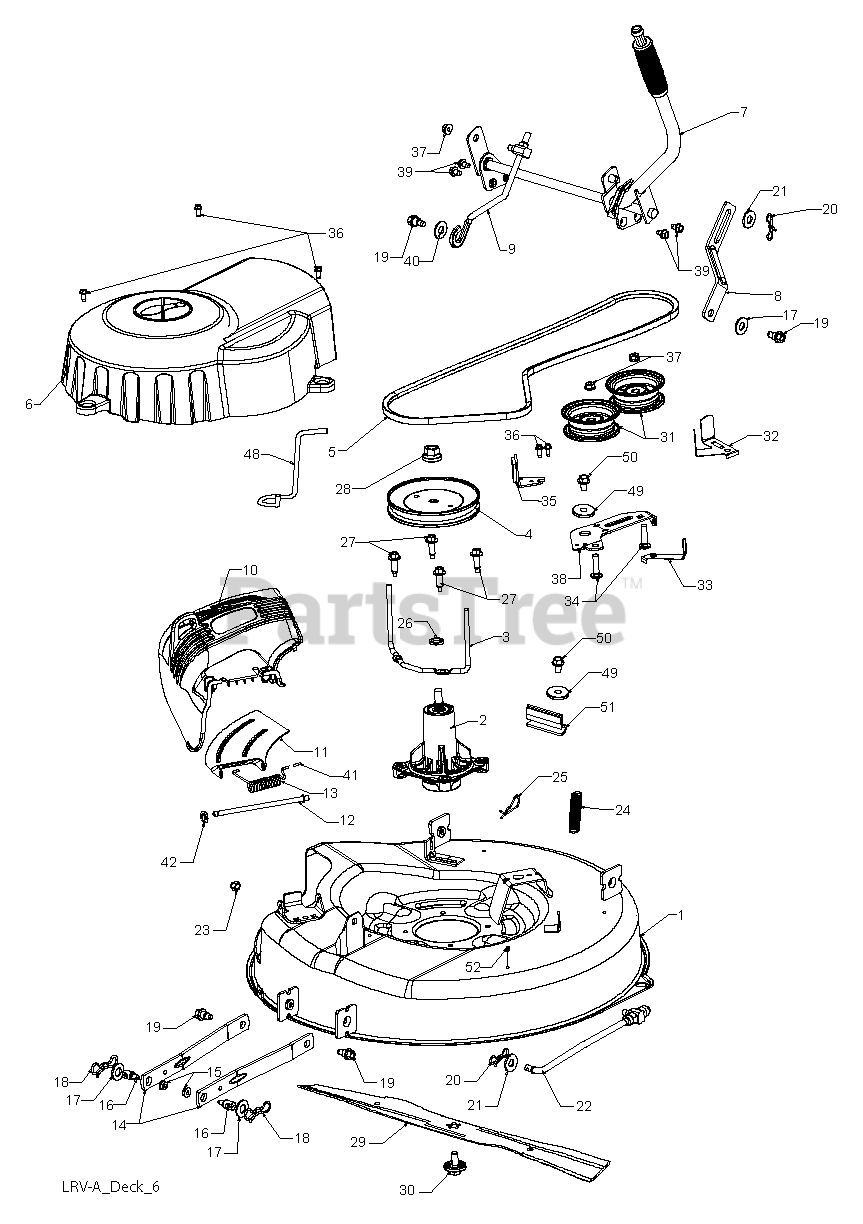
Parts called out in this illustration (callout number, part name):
1	DECK, 26"
2	MANDREL.ASM.SUB-NON.GR
3	KEEPER.BELT.MANDREL.PULLEY
4	PULLEY.MANDREL
6	COVER, MANDREL
7	LIFT.ASM.DECK.LRV
8	LINK, DECK LIFT
9	LINK.ASM.LIFT.ADJUSTABLE
11	SUPPORT, DEFLECTOR
12	ROD.HINGE
13	SPRING.TORSION.DEFLECT
14	ARMS.SUSP.MOWER.REAR.SRD
15	NUT LOCK HEX FLANGE 5/16-18
16	STUD.FASTNER.W/ANTI-ROTATE
17	WASHER.CLEAR.ZINC
18	PIN.COTTER.7/16.BOW TI.
19	BOLT.SHOULDER
20	PIN.COTTER.5/16.BOW TI
22	LINK.ASM.TOP.DECK.LRV
23	NUT LOCK FLG 3/8-16 UNC
24	SPRING.EXTENSION.DECK.LRV
26	WASHER.SPACER.MANDREL
27	SCREW, WASHER HEAD
28	NUT.FLANGE.LOCK.TOP
29	BLADE.26"
30	BOLT.WASHER.ASM.7/16-2
31	PULLEY.IDLER.48"PRIMARY
32	GUARD, BELT
33	KEEPER BELT
34	BOLT.3/8-16X1.50
35	ARM BRAKE MOWER RH
36	SCREW.1/4-20X5/8
37	NUT LOCK FLG 3/8-16 UNC
38	ARM, IDLER
39	SCREW LT
41	CAP-SLEEVE LT
42	NUT PUSH M
48	KEEPER.BELT
49	SPACER.RETAINER
50	SCREW 3/8-16X1
51	BUMPER.HOOD.TEX.HUSQVARNA
52	SCREW 3/8-16X1/2
